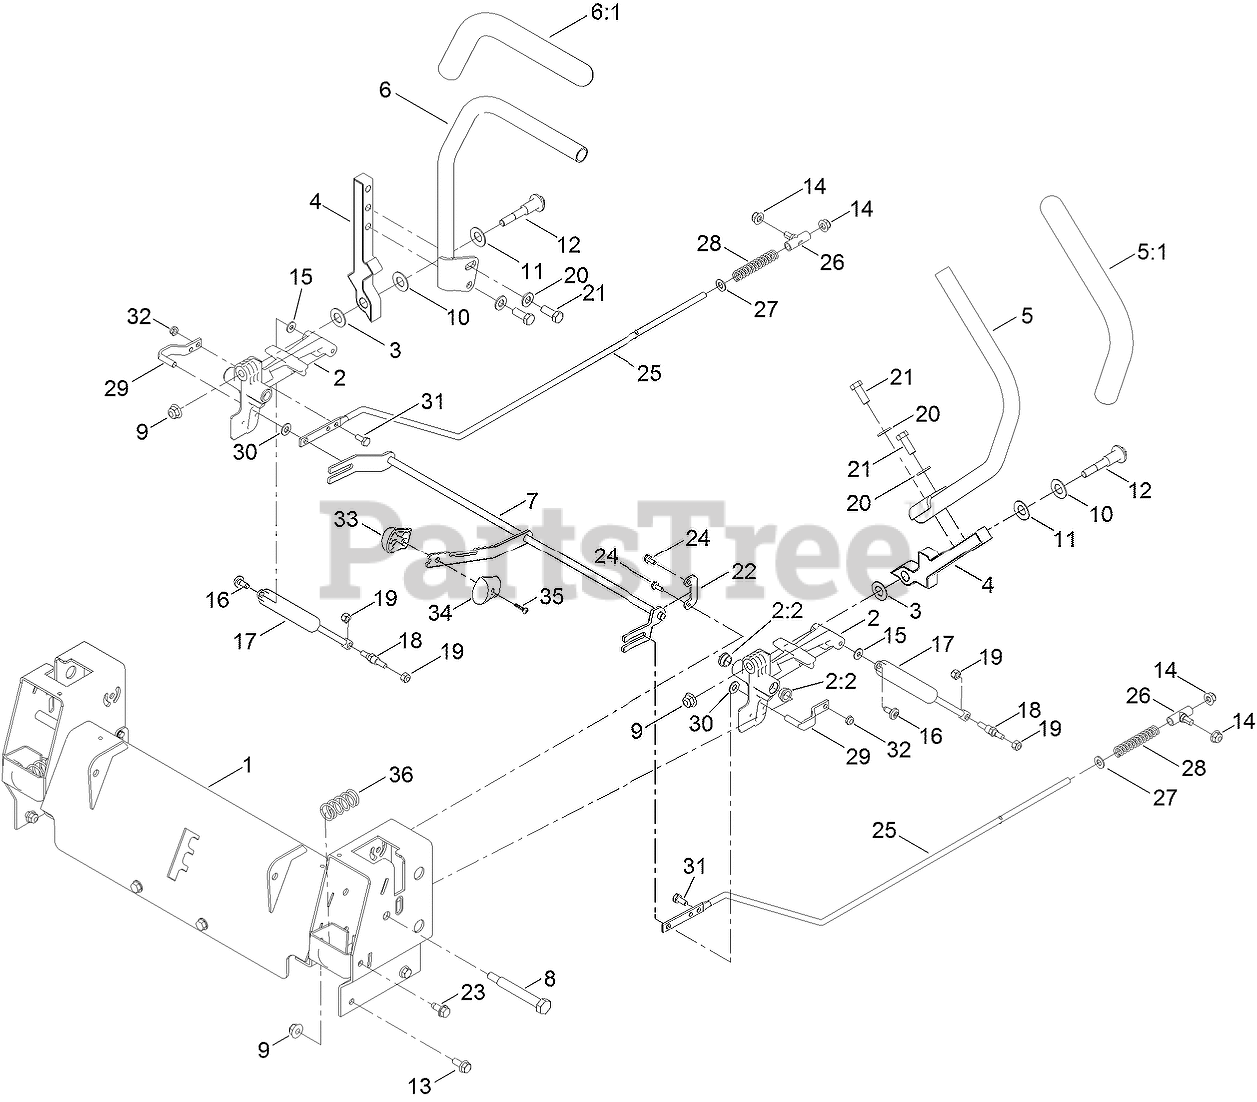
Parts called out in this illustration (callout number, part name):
1	CONTROL BOX ASM
2	ACTUATOR ARM ASM
2:2	BUSHING-FLANGE
3	WASHER-NYLON
4	ARM-CONTROL
5	HANDLE-CONTROL, LH
6	HANDLE-CONTROL, RH
7	SPEED CONTROL ASM
8	BOLT-PIVOT
9	NUT-HF, NI
10	WASHER
11	WASHER-BELLEVILLE
12	BOLT-PIVOT
13	SCREW-HHF
14	NUT-HF, NI
15	WASHER
16	SCREW-SHOULDER
17	DAMPER
18	STUD-DAMPER
19	NUT-LOCK, NI
20	WASHER-FLAT
21	SCREW-HH
22	RETAINER
23	SCREW-HWHTF
24	SCREW-TAPTITE
25	ROD-HYDRO
26	MOUNT-ROD, HYDRO
27	WASHER-PLAIN
28	SPRING-RETURN, NEUTRAL
29	PIN-ROD, HYDRO
30	SPACER-NYLON
31	SCREW-HH
32	NUT-LOCK, NI
33	KNOB-RH
34	KNOB-LH
35	SCREW-PPH
36	SPRING-RETURN
